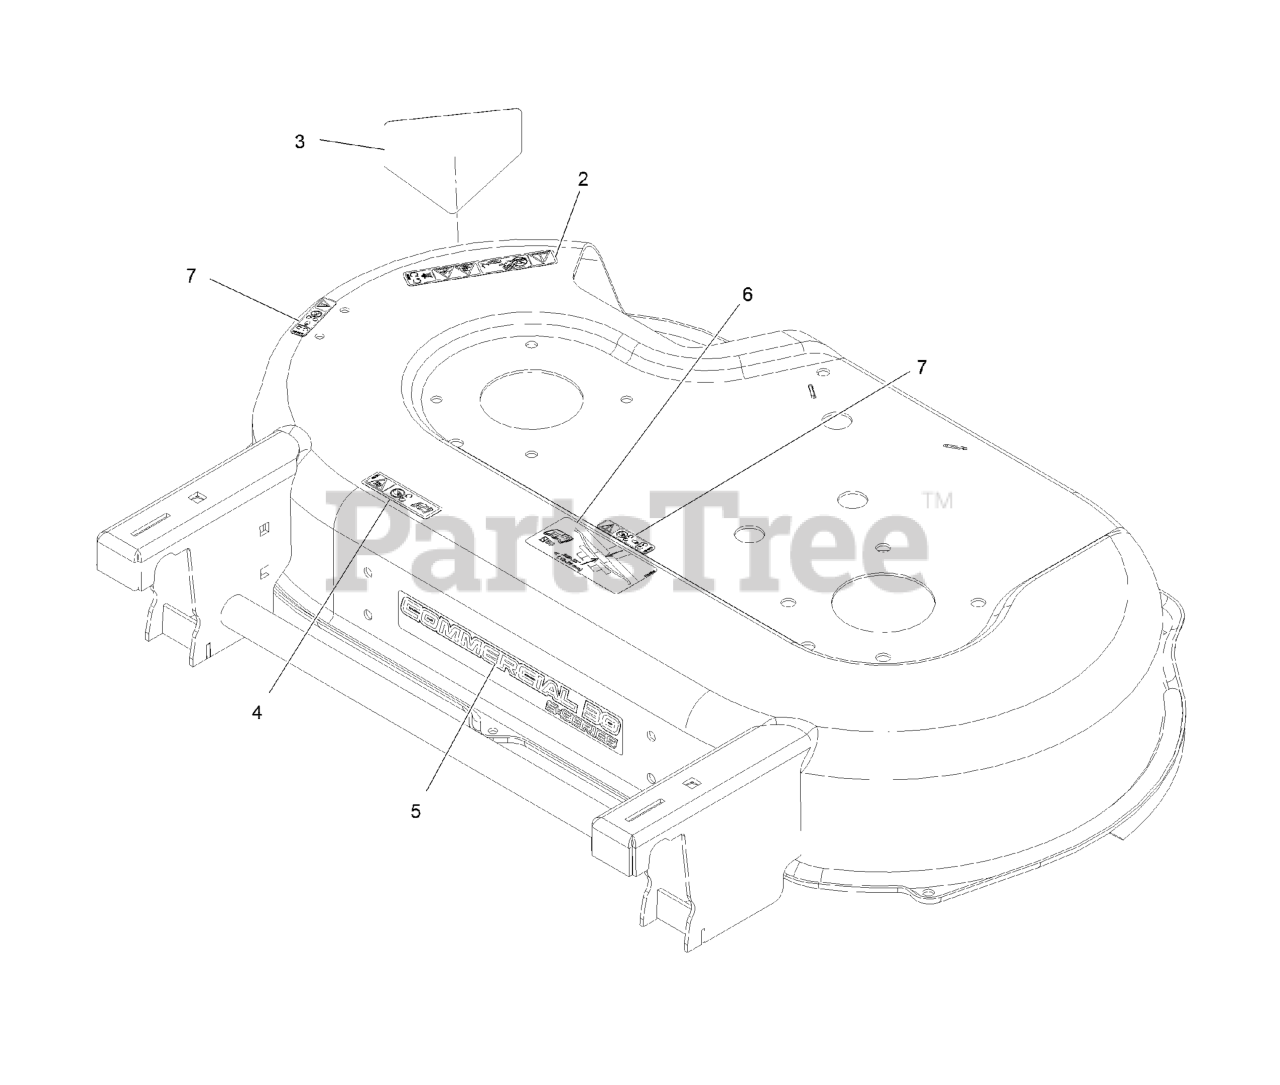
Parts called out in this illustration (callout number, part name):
2	DECAL-DANGER
3	DECAL-DANGER
4	DECAL-WARNING
5	DECAL-COMM 30 S-SERIES
7	DECAL-WARNING
